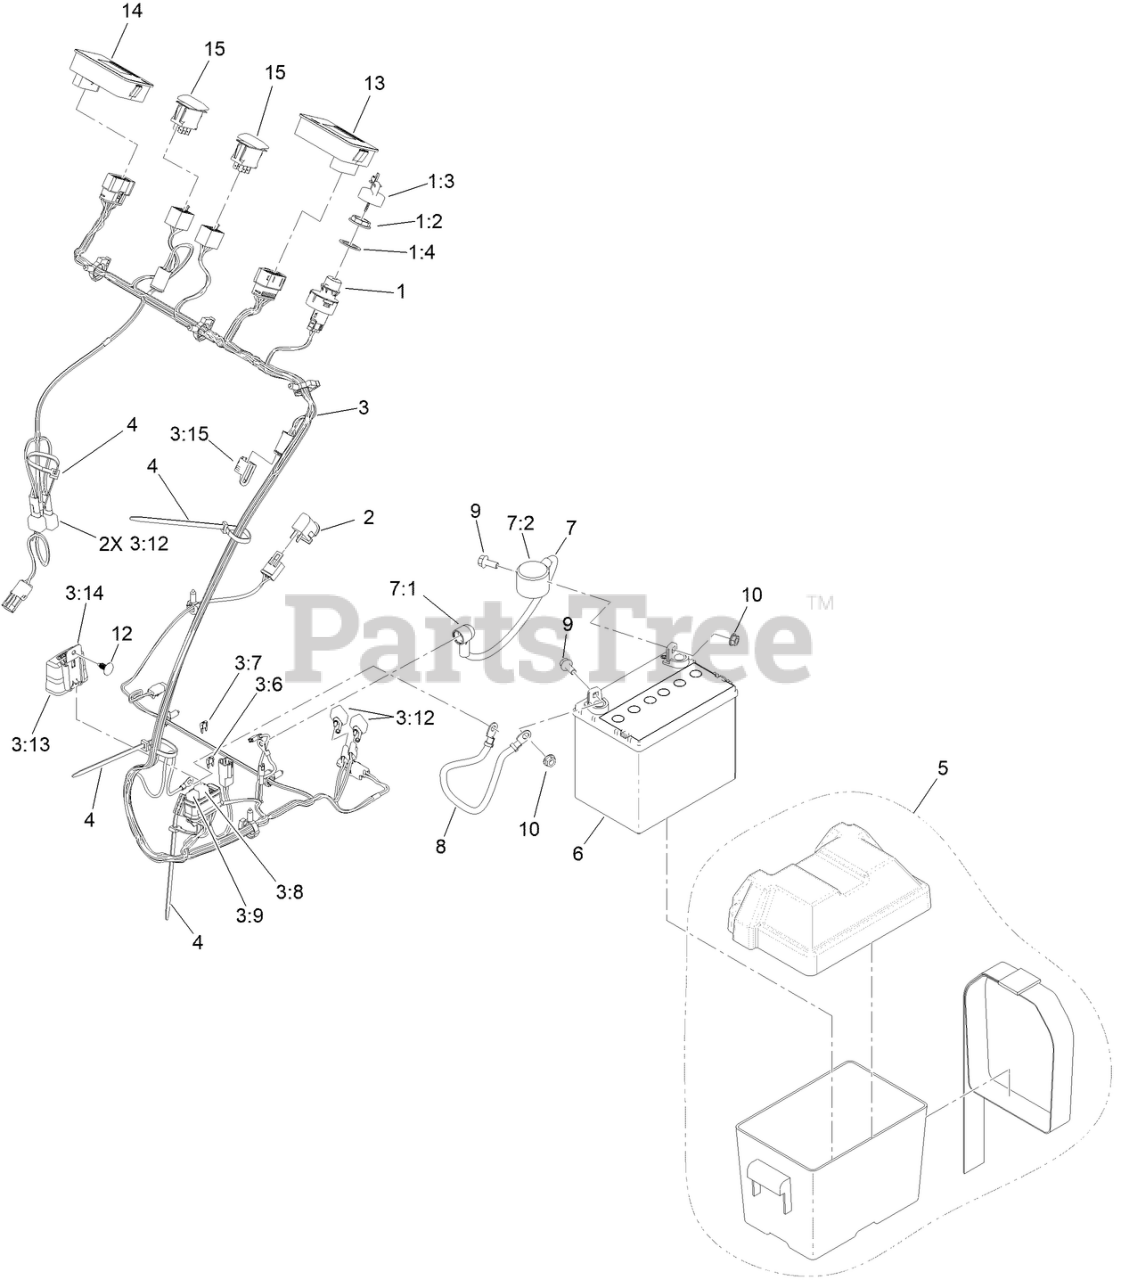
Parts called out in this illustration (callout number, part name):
1	IGNITION SWITCH ASM
1:2	NUT-MOUNTING
1:3	IGNITION KEY SET
1:4	WASHER-BACKUP
2	SWITCH-BAIL
3	Harness-Wire
3:6	FUSE-MINI BLADE, 20 AMP
3:7	FUSE-MINI BLADE, 25 AMP
3:8	RELAY-MICRO
3:9	Relay-Coil, NC, Mp280
3:12	DIODE-OVERMOLDED, 6A, FAST RECOVERY
3:13	COVER-BLOCK, FUSE
3:14	CLIP-MOUNTING
3:15	CAP-PLUG, 6 WAY
4	TIE-CABLE
5	BATTERY BOX
6	Battery- Wet, 12V, 300 CCA
7	Positive Battery Cable ASM
7:1	INSULATOR-SOLENOID
7:2	INSULATOR-BATTERY
8	CABLE-BATTERY, NEGATIVE
9	SCREW-HHF
12	PLUG-PLASTIC
13	Hour Meter ASM
